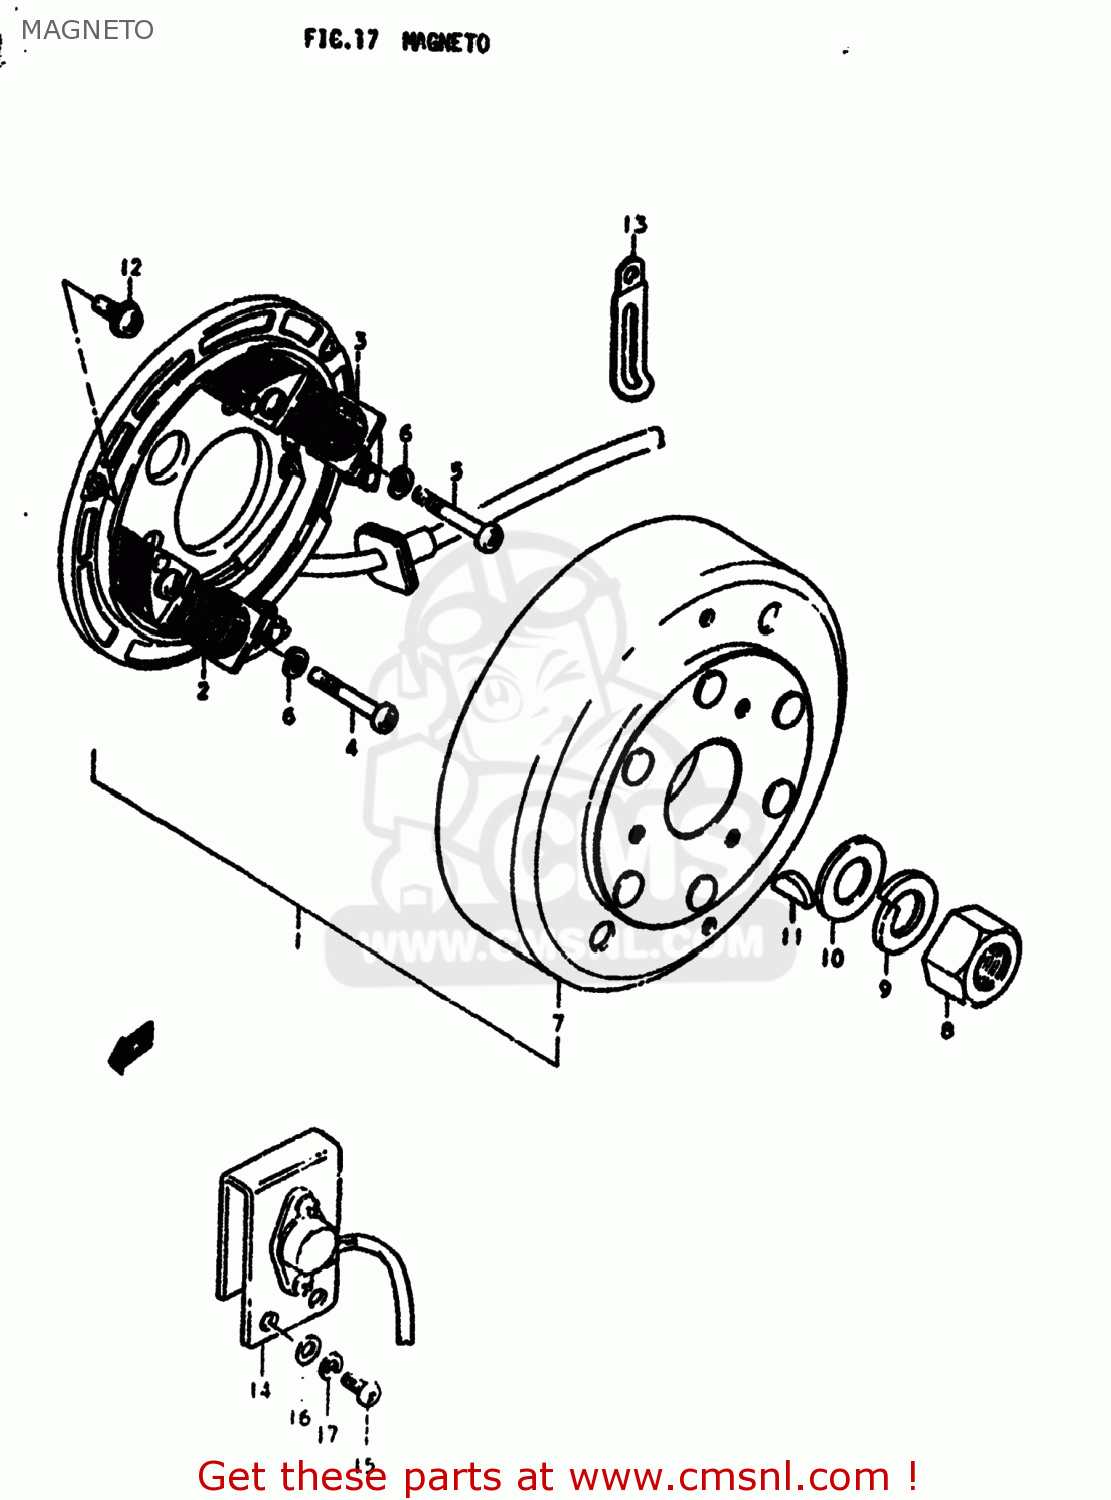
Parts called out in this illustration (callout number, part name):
1	MAGNETO ASSEMBLY
2	COIL,LIGHTING
3	COIL,PRIMARY
4	SCREW
5	SCREW
6	LOCK WASHER
7	ROTOR ASSEMBLY
8	NUT
9	LOCK WASHER
10	WASHER(14X27X3)
11	KEY 4MM
12	SCREW(5X14)
13	CLAMP
14	REGULATOR ASSEMBLY
15	SCREW
16	WASHER
17	LOCK WASHER
